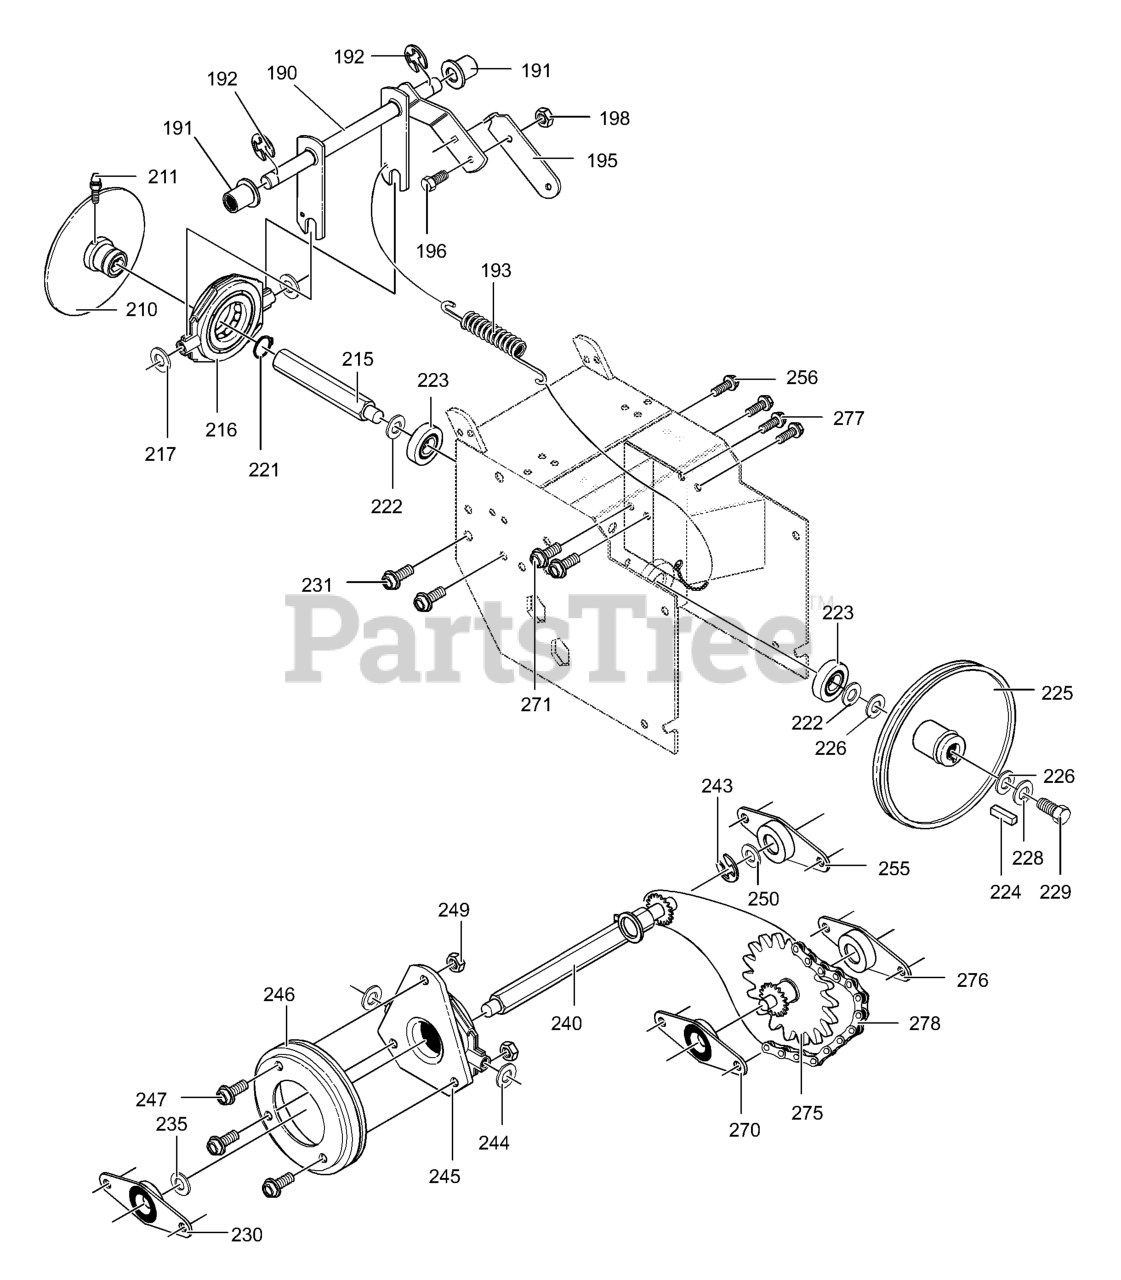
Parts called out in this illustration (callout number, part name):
190	LEVER, ASSY TRACTION CLUTCH
191	BEARING, FLANGE
192	RING, RET E
193	SPRING, RETURN
195	LEVER, SPRING
196	SCREW, 1/4-20X .63
198	NUT, 1/4-20
210	DISC, ASSY
211	ZERK, GREASE
215	SHAFT, HEX TRACTION
216	BEARING, TRUNION
217	FLATWASHER
221	RING, RETEX
222	FLATWASHER
223	BEARING, BALL
224	KEY, SQUARE
225	PULLEY, V3L 6.50X .56
226	WASHER, WAVE
227	FLATWASHER
230	BEARING & RETAINER
231	SCREW, 5/16-18 x 0.50
240	HEX, ASSY #40-8T
243	RING, RETEX
244	FLATWASHER
245	BEARING, TRUNION
246	WHEEL, ASSY FRICTION
247	SCREW, 1/4-20X .63
249	NUT, 1/4-20 HEX KEPS
255	BEARING & RETAINER
256	SCREW, 5/16-18 x 0.50
270	BEARING & RETAINER
271	SCREW, 5/16-18 x 0.50
275	JACK, ASSY
276	BEARING & RETAINER
277	SCREW
278	CHAIN ROLLER
